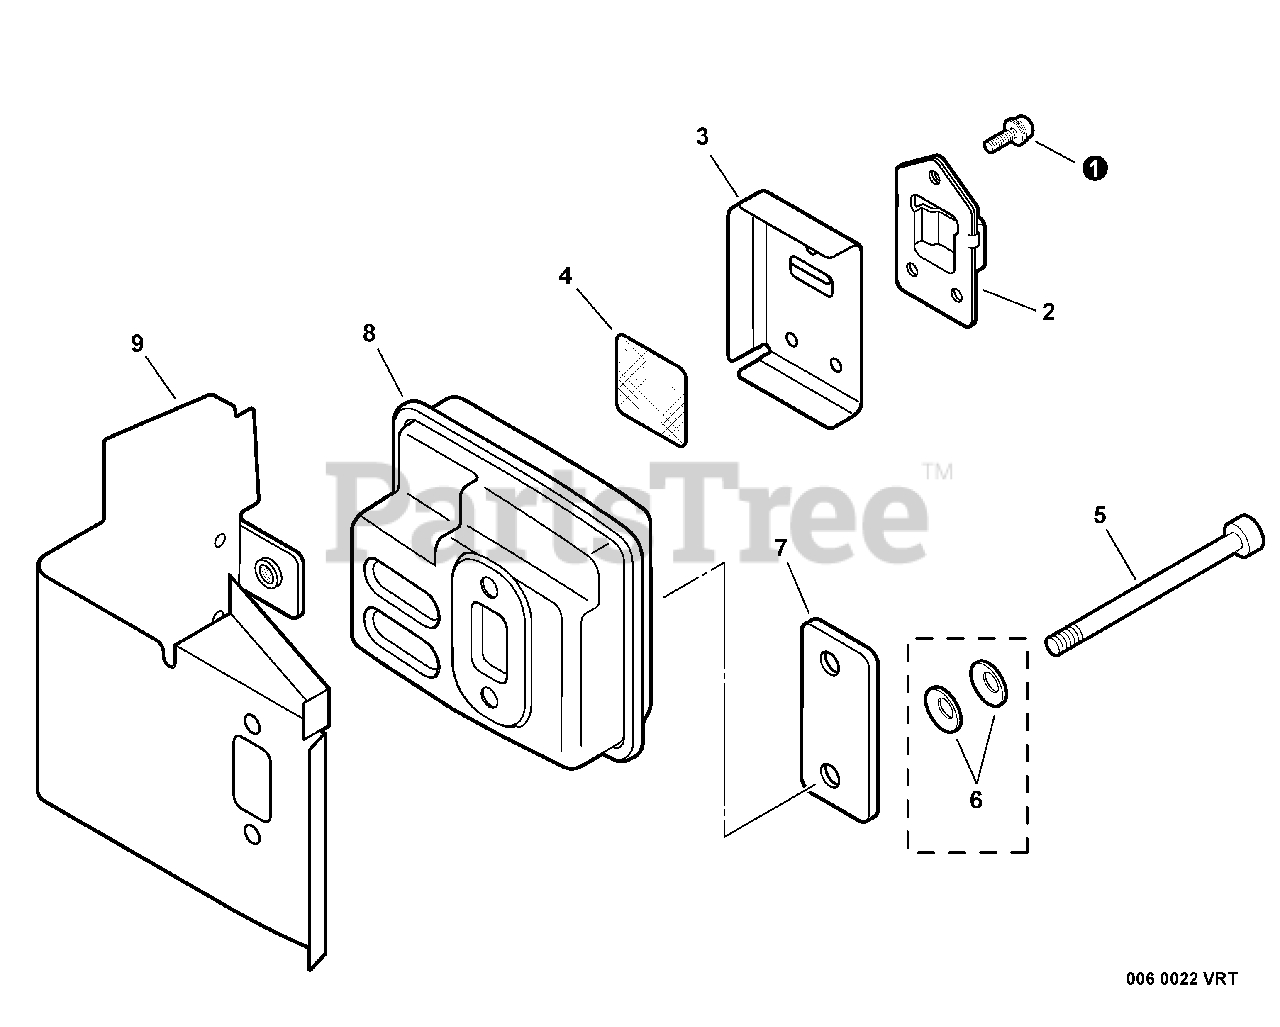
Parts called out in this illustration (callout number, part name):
1	SCREW - 4X12
2	GUIDE, EXHAUST
3	GASKET, EXHAUST
4	SCREEN, SPARK ARRESTOR
5	SCREW - 5X55
6	WASHER - CONICAL
8	MUFFLER
9	SHIELD, EXHAUST
